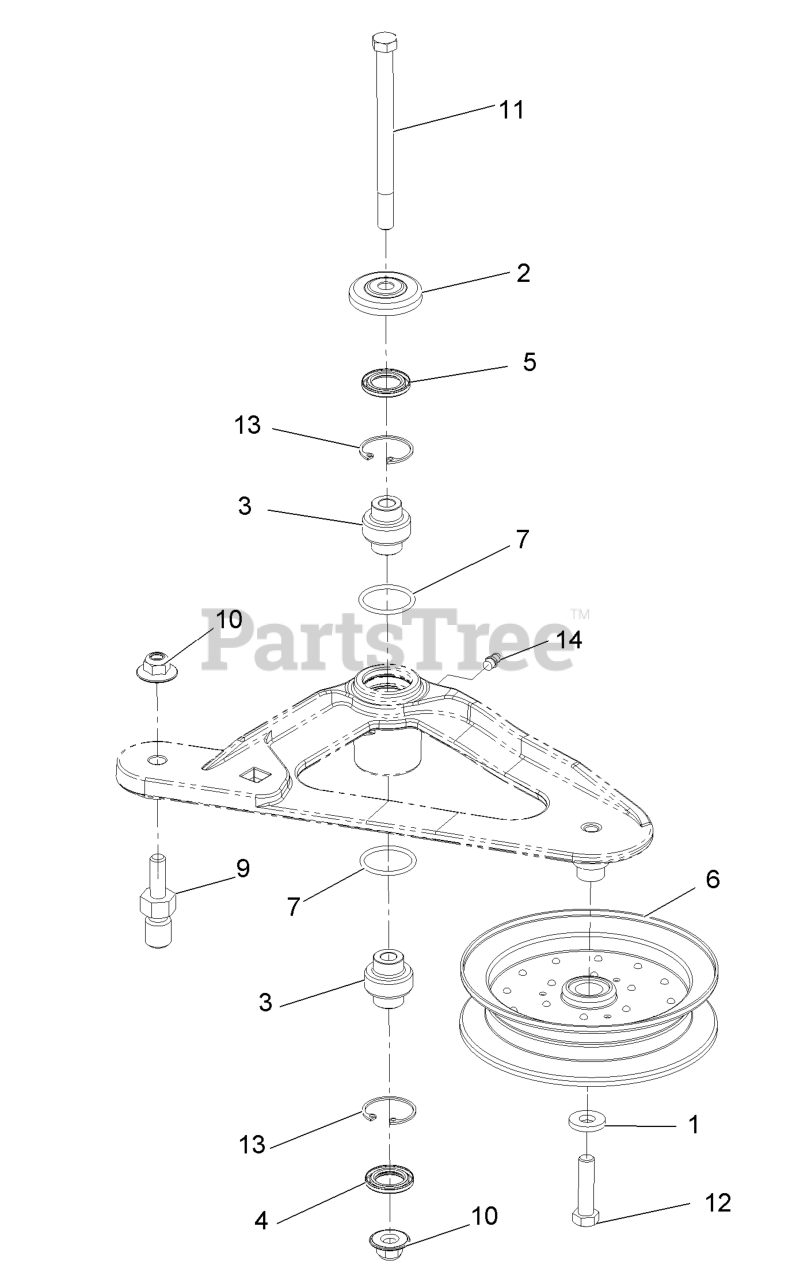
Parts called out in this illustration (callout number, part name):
2	GUARD-TOP
3	BEARING-SPHERICAL
4	SEAL-LIP, DOUBLE
5	SEAL-LIP, SINGLE
10	Nut-Nyloc 3/8-16 Flg
11	SCREW-SHOULDER, HH
12	SCREW-HH
13	RING-SNAP
14	FITTING-GREASE
